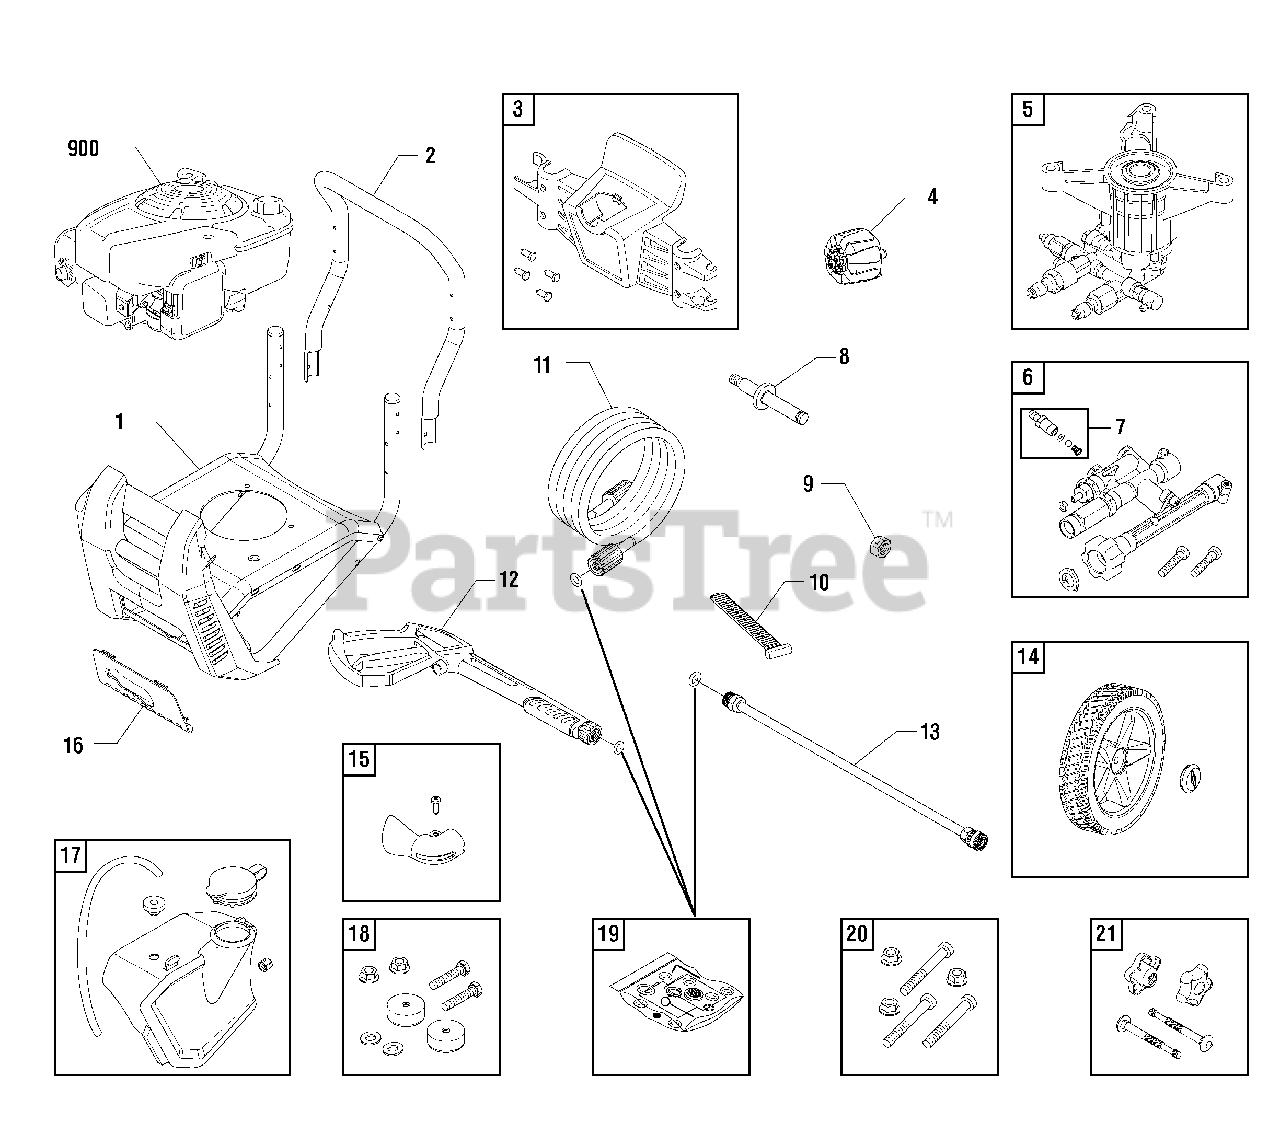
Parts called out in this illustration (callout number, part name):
5	PUMP
12	GUN
15	DEFLECTOR-EXHAUST
17	TANK-CHEMICAL
18	MOUNT-VIBRATION
20	KIT-HARDWARE PUMP MOUNTING
21	KIT-HARDWARE HANDLE
900	** ENGINE
